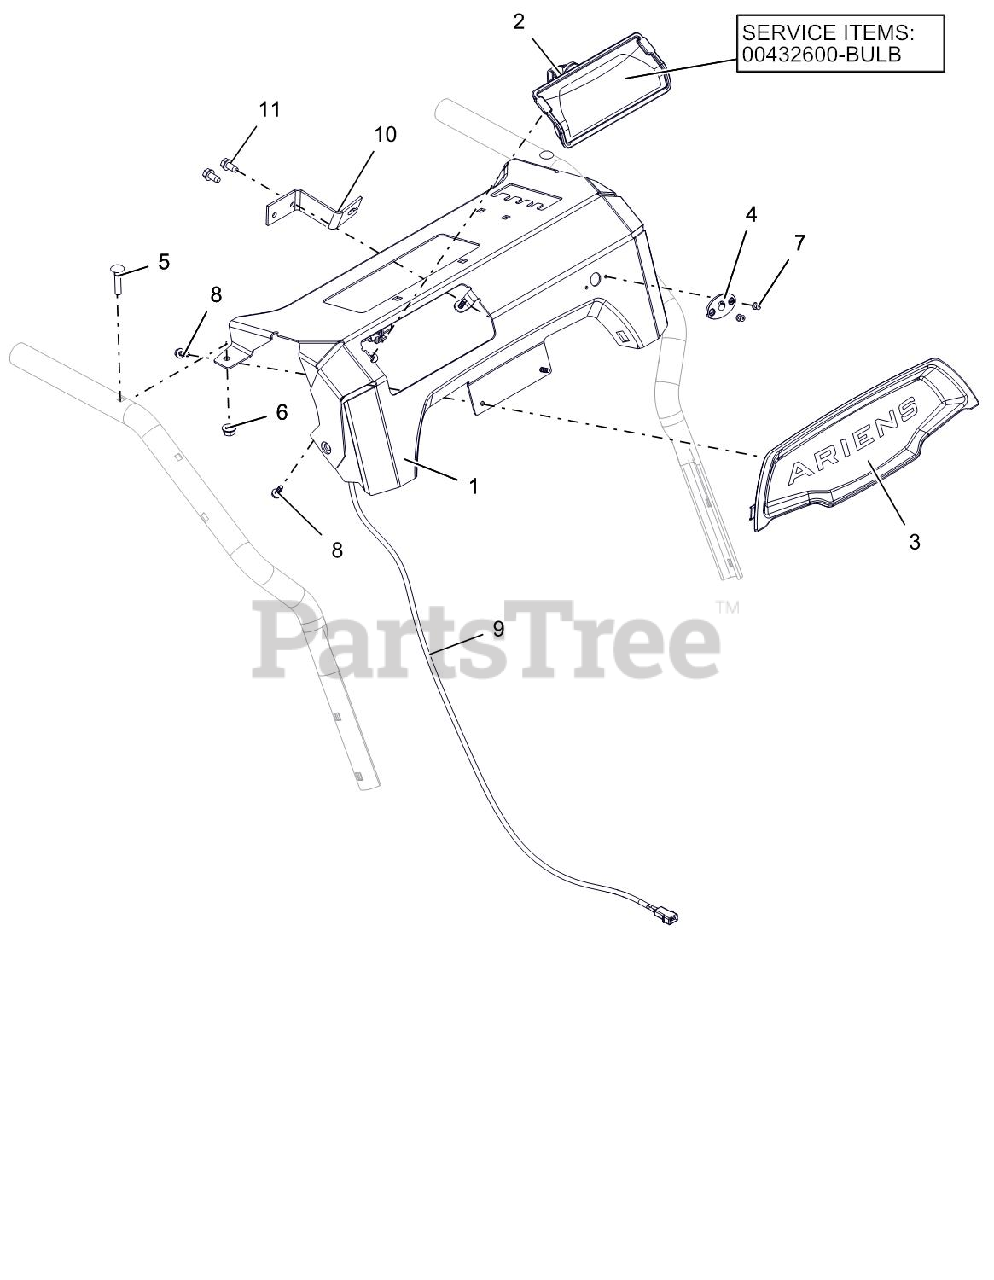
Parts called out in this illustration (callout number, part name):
1	CTRL PANEL W/DECAL-SM DASH DLX
2	BULB, LIGHT-HALOGEN 20W
2	HEADLIGHT ASY, HALO 20W 2SHOT
3	BEZEL, DASH - ARIENS SM DASH
4	BSHG, CHUTE CRANK
5	BLT-RDHDXLSQNK.25-20X1.25 G5ZC
6	@NUT-LK-TOP-FLG .25-20 YWZC
7	RVT-POP #43 .125X.313 STL ZINC
8	SCR-TAP #10X.50 BOSS INDHXHD
9	HARNESS, LIGHT - COMPACT
10	ANCHOR, DEFLECTOR CABLE
11	SCR-TAP .25-20X.50 HWH TR YWZ
